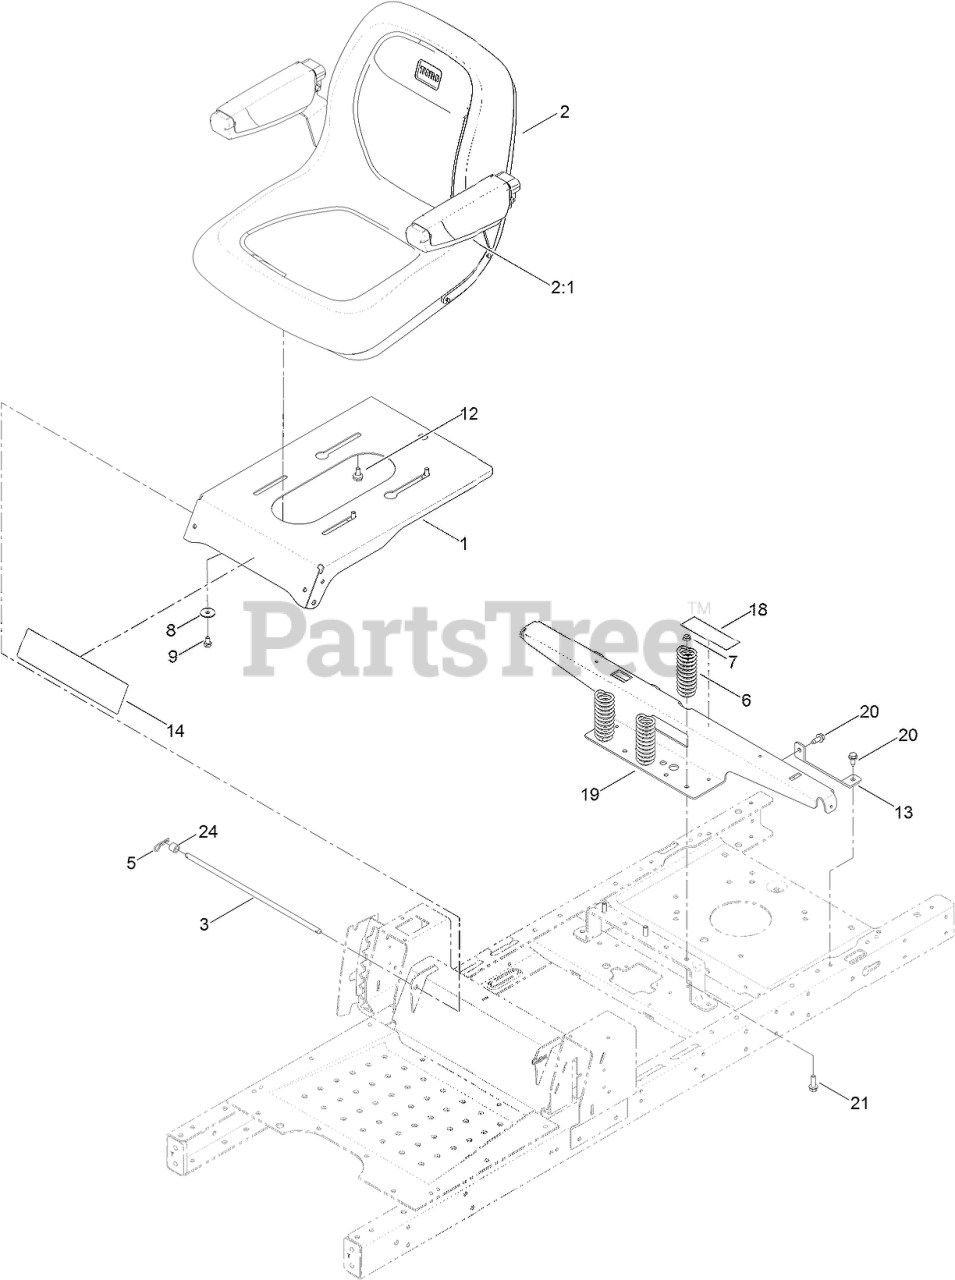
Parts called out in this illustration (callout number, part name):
1	PAN-SEAT
2	SEAT-18 Inch
2:1	ARMREST KIT (MILSCO)
3	ROD-STOP
5	PIN-COTTER
6	SPRING-COMPRESSION
7	NUT-HF, NI
8	WASHER-PIVOT
9	SCREW-HH
12	BOLT-SHOULDER
13	SUPPORT-TANK, REAR
14	DECAL-TIMECUTTER
18	DECAL-SERVICE, CE
19	SUPPORT-POD, WIDE
20	SCREW-HWHTF
21	SCREW-HHF
24	BUSHING-LEVER, LIFT
